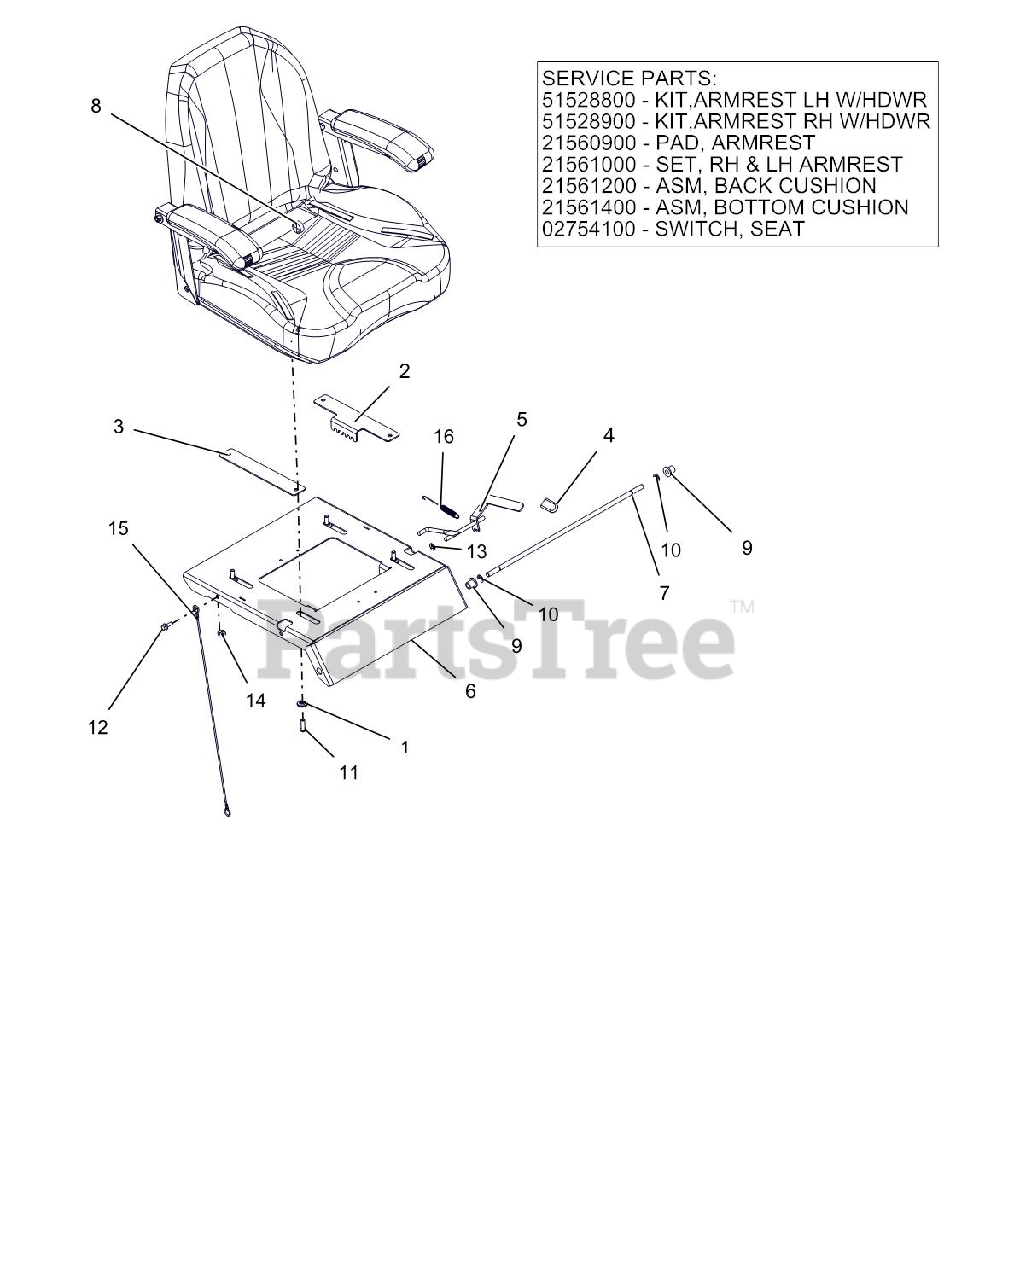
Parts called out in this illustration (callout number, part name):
1	BSHG, FLG .325X.499X.26X.88
2	PLATE, ADJUSTABLE SEAT TRACK
3	PLATE, ADJUSTABLE SEAT SLIDE
4	GRIP, SEAT LEVER, GREY
5	WLDMT, ADJUSTABLE SEAT LATCH
6	PLATE, SEAT
7	ROD, SEAT PIVOT
8	SWITCH- SNAP MTG N.O.
8	KIT, ARMREST LH
8	KIT, ARMREST RH
8	PAD, ARMREST (HARD)
8	SET,RH & LH ARMREST -HARD
8	ASM,BACK CUSHION-ARIENS X
8	ASM,BOTTOM CUSHION-ARIENS X
8	SEAT, IKON
9	BSHG-FLG .38X.580X.667X.750
10	RG-RTNG-EXT .375X.035 TYP E
11	SCR-SKH .31-18X1.0 BTNHD YWZC
12	BLT,HEX-FLG .25-20X.75 G5 BFP
13	NUT-PUSH .312
14	@NUT-LK-NYL-FLG .31-18 YWZC
15	LANYARD, SEAT CABLE .093X19.5
16	SG-TENS .043X.44X3.31 WLD 5.8
